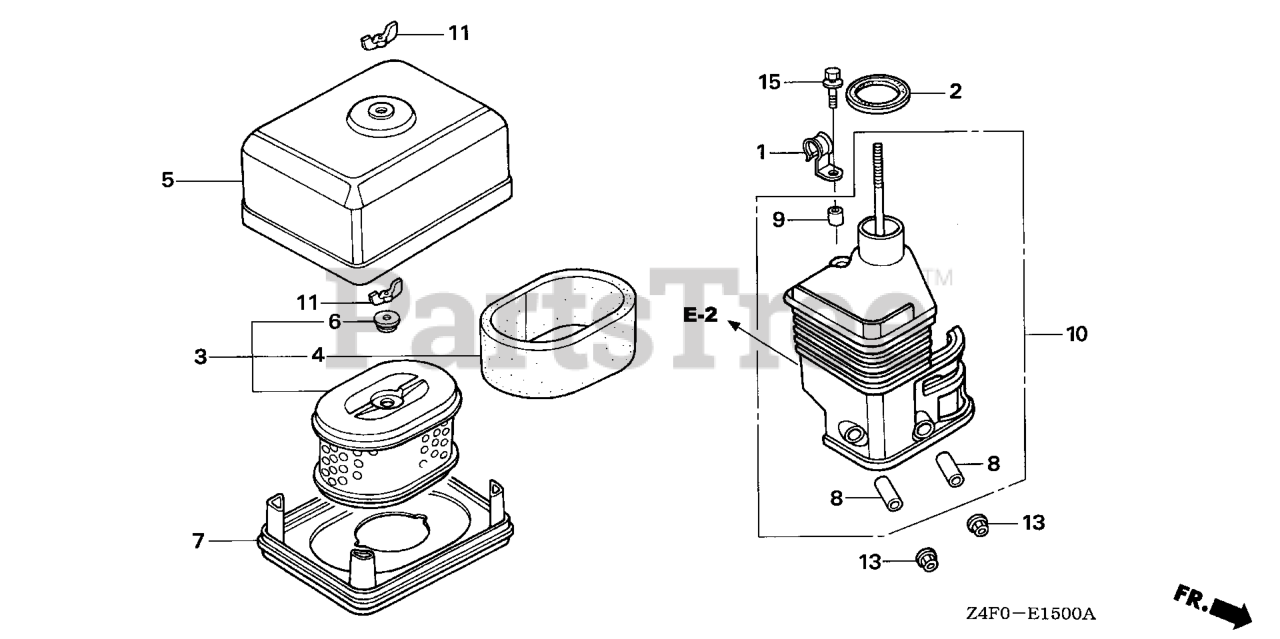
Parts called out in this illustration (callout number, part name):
2	GASKET, ELBOW
3	ELEMENT, AIR CLEANER (DUAL)
4	FILTER (OUTER)
5	COVER, AIR CLEANER (DUAL)
6	GROMMET, AIR CLEANER
7	NOSE, MUFFLER
8	COLLAR, AIR CLEANER
9	COLLAR B, AIR CLEANER
10	ELBOW, AIR CLEANER
11	WINGNUT, TOOL BOX SETTING
13	NUT, FLANGE (6MM)
15	BOLT, FLANGE (6X20)
